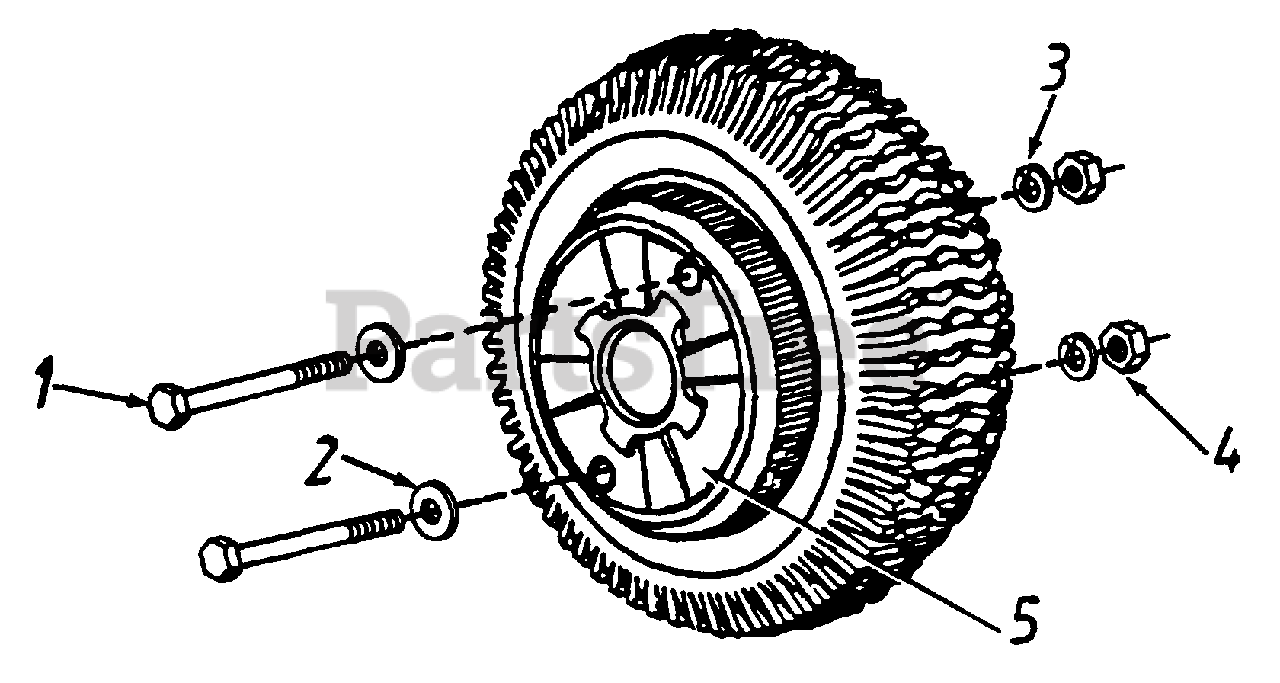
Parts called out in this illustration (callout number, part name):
1	Hex Bolt 3/8-16 x 7-1/2" Lg.
2	Fl-Wash. 3/8" I.D.
3	L-Wash. 3/8" l.D.
4	Hex Nut 3/8-16 Thread
5	31 Lb. Wheel Weights
